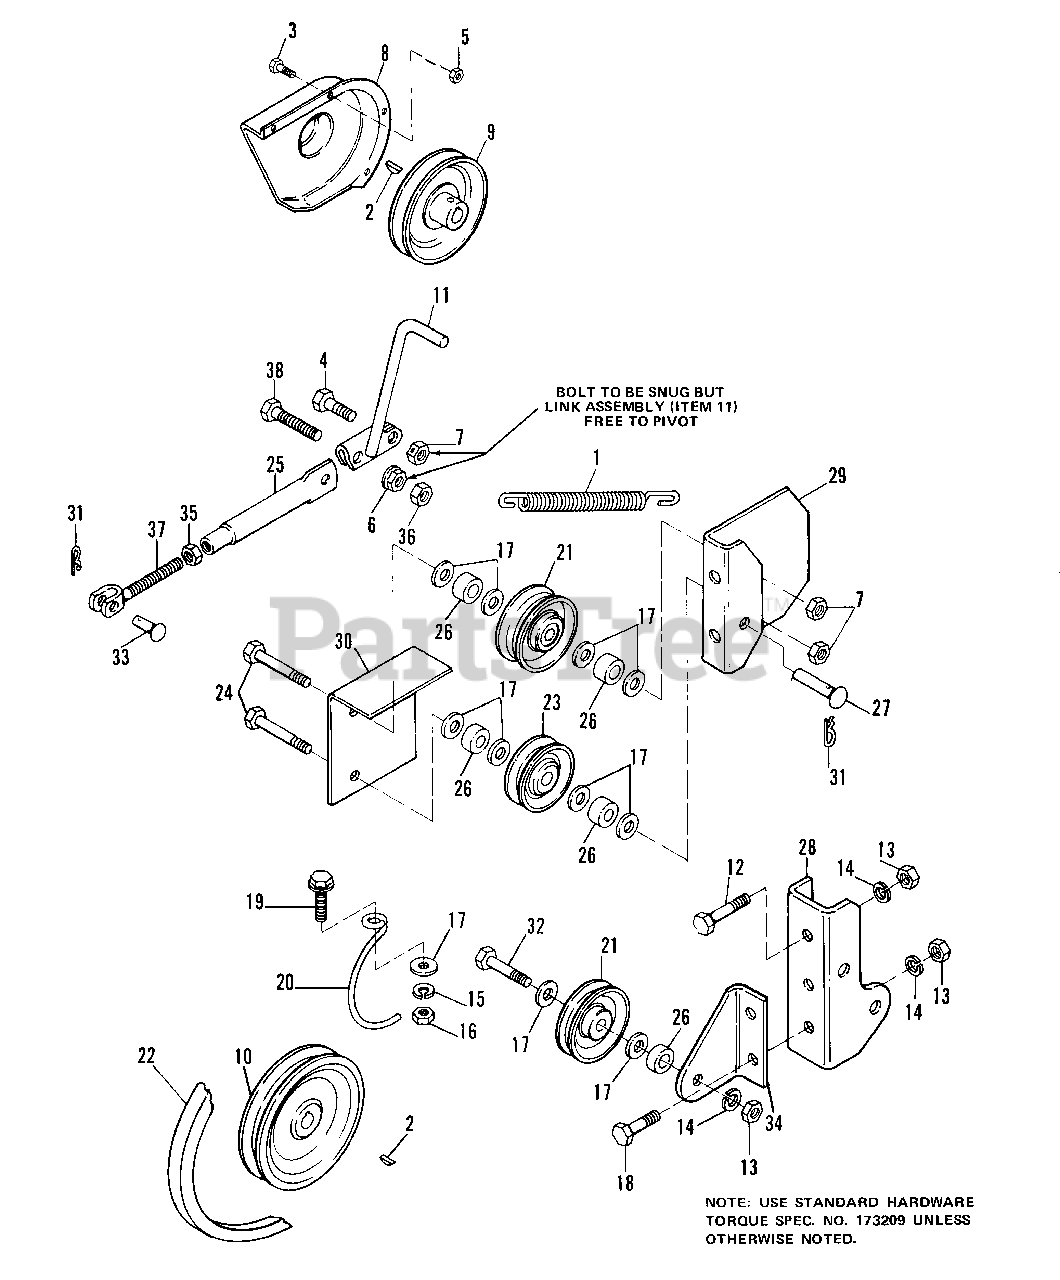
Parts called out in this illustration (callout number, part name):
2	KEY, Woodruff, No. 9, 3/16 x 3/4
3	CAPSCREW, Hex, 1/4-20 x 1/2
4	CAPSCREW, Hex, 3/8-16 x 1
5	LOCKNUT, Hex, Full, 1/4-20
6	LOCKNUT, Hex, Full, 3/8-16
7	LOCKNUT, Hex, Full, 3/8-16
8	GUARD, Belt-Pulley
9	PULLEY (Driven)
10	PULLEY, (Driven)
11	LEVER ASSY, Clutch
12	CAPSCREW, Hex, 3/8-16 x 3/4
13	NUT, Hex, Full, 3/8-16
14	LOCKWASHER, 3/8
15	LOCKWASHER, 5/16
16	NUT, Hex, Full, 5/16-18
17	WASHER, Plain, 5/16
18	CAPSCREW, Hex, 3/8-16 x 7/8
19	SCREW, Lock, Flange, 5/16-18 x 3/4
20	STOP, Belt
21	PULLEY, Idler
23	PULLEY, Idler
24	CAPSCREW, Hex, 3/8-16 x 2
25	LINK, Clutch
28	BRACKET, Pulley Support
29	SUPPORT, Pulley
30	GUARD, Idler Pulley
31	CLIP, Pin
32	CAPSCREW, Hex, 3/8-16 x 1-1/2
33	PIN, Lock
34	BRACKET, Pulley
35	NUT, Hex, Full, 7/16-14
36	LOCKNUT, Hex, Half, 3/8-16
37	CLEVIS ASSY, Adj.
38	CAPSCREW, Hex, 3/8-16 x 1-3/4
